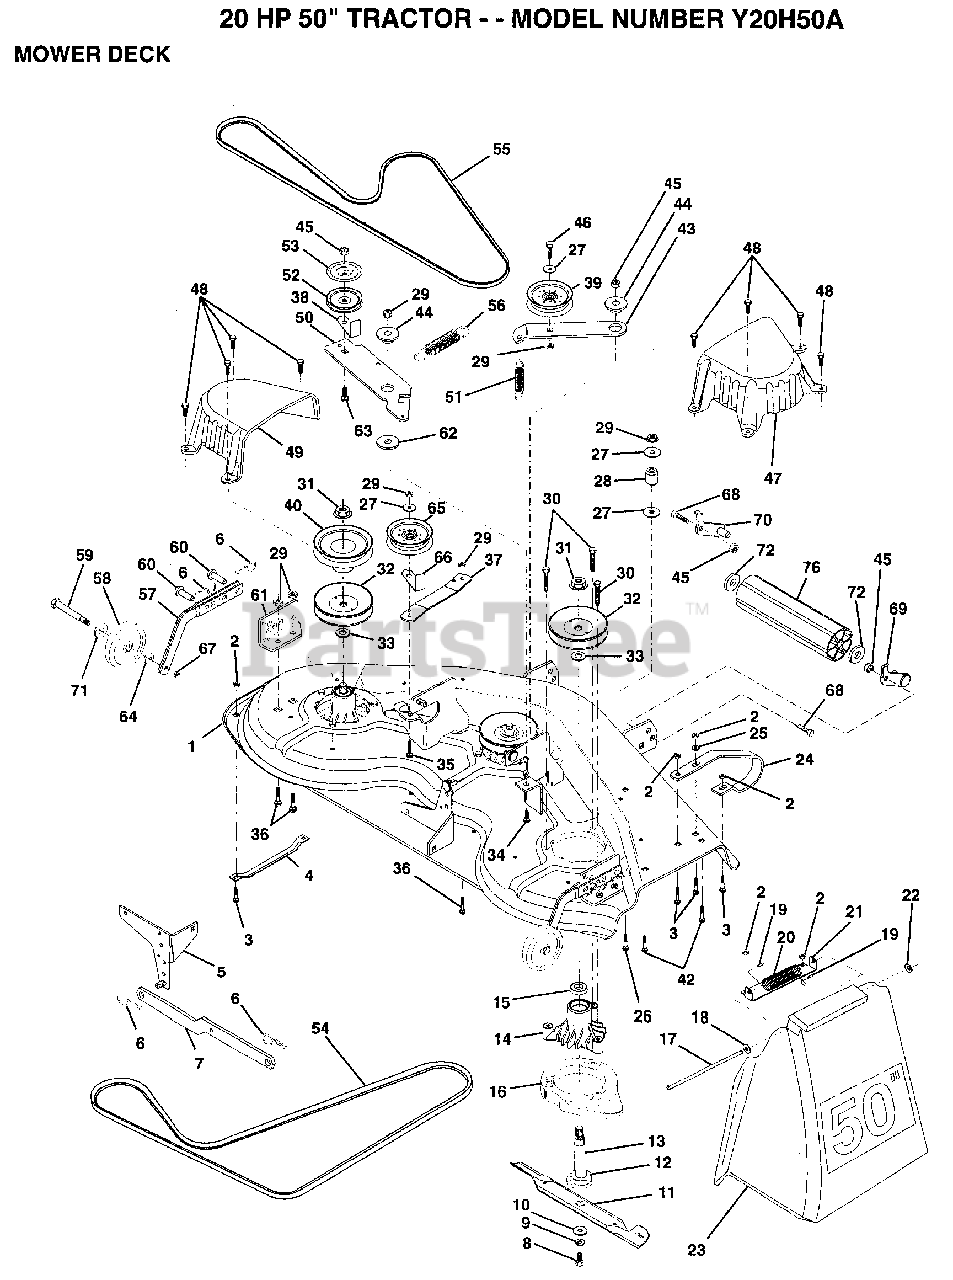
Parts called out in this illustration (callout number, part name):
1	DECK ASM MWR 50VT
2	NUT
4	RUNNER-LH M
5	BRKT.ASM.SW.44/50
8	BLADE BOLT
10	WASHER.HARD.BLADE
11	"BLADE.50"" HD"
12	BEARING.BALL
13	SHAFT.ASM.W/BRNG
14	HOUSING.MAND.44.V
15	BEARING
17	ROD-HINGE T
18	WASHER
19	CAP-SLEEVE LT
20	SPRING TORSION
21	BRKT DEFLECTOR
22	NUT PUSH M
23	DEFLECTOR
24	"RUNNER RH 50"" DK"
25	WASHER M
26	BOLT
27	WASHER
29	NUT
33	WASHER
34	BOLT.3/8-14X1.25
35	BOLT
36	BOLT D
37	STIFFENER.ARM.IDL
39	FLAT IDLER PULLEY
40	"PULLEY.DRIVEN.44"""
42	BOLT
43	"ARM.IDLER.SEC.44"""
44	SPACER RETAINER
47	"COVER.MAND.RH.44"""
48	SCREW.1/4-20X5/8
49	COVER.MANDREL.LH
50	ARM.IDLER.PRIMARY
51	"SPRING.SEC.44""VEN"
52	PULLEY.IDLER.VGRO
53	SHIELD.IDLER.44.V
54	BELT V PRIM 50
55	BELT.V.GDRIVE.95
56	SPRING.EXT.DECK.
57	BAR.ASM.GUAGE.WHL
58	WHEEL.GAGE.BLK.PL
59	BOLT M
60	PIN.CLEVIS
61	BRACKET.GUAGE.WHL
62	HARDENED WASHER
63	BOLT.3/8-16X1.50
64	WASHER
65	IDLER-FLAT T
67	LOCKNUT
68	BOLT
71	WASHER
72	WASHER
